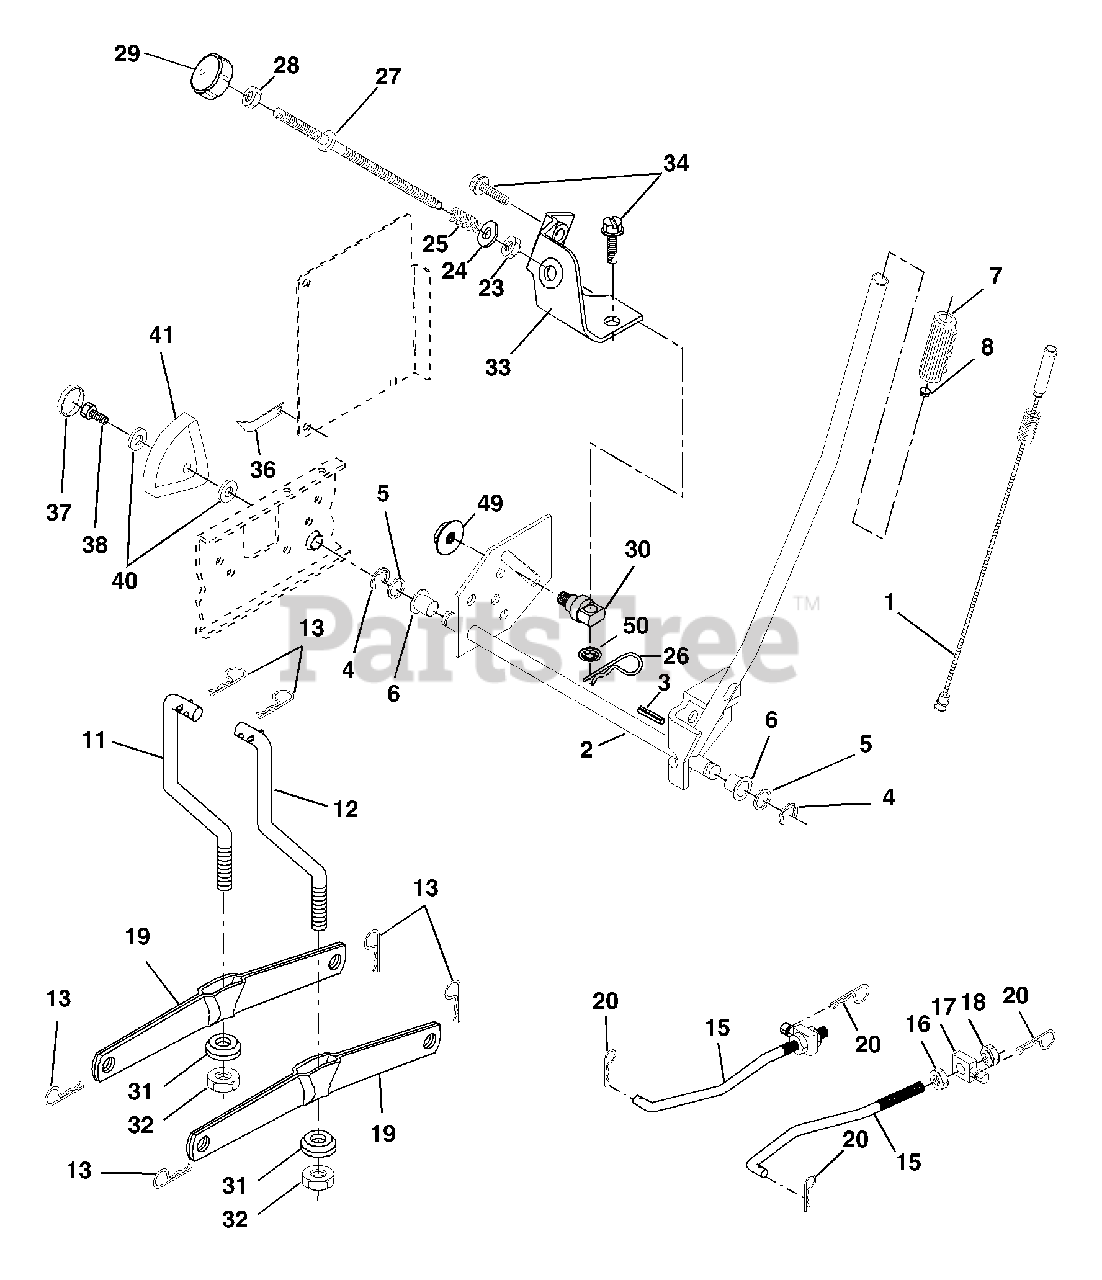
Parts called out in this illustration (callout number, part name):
1	Wire Asm Inner/Sprg W/plunger LT
2	Shaft Asm Lift RH w/Inf
3	Pin Groove 1 500 Zinc
4	E Ring #5133-62
5	Washer 21/32 X 1 X 21 Ga
6	Bearing Nylon Blk 629 Id
7	Grip Handle
8	Button Plunger
11	Link Lift LH Fixed Length
12	Link Lift RH Fixed Length
13	Retainer Spring
15	Link Front
16	Nut Jam Hex 1/2-13 Unc
17	Trunnion Blk Zinc
18	Nut Lock w/Wsh 1/2-13unc
19	Arm Suspension Rear
20	Retainer Spring
23	Nut Special
24	Washer 13/32 X 5/8 X 16 Ga
25	Spring 2-1/8"
26	Retainer Clip
27	Rod Adj Lift Zinc 7.49 Wrk Lg
28	Nut Hex Jam 3/8-16 Unc
29	Knob Inf 3/8-16 Unc Blk W/sym
30	Trunnion Infin Height
31	Bearing Pvt Lift Spherical
32	Nut Crownlock 3/8 - 24
33	Bracket Infinite Height
34	Screw Thdrol 3/8-16 x 1/2
36	Pointer Height Indicator
37	Plug Hole Blk 1.485/1.515 Dia.
38	Screw 5/16-18 x 1
40	Washer 11/32 x 1-1/2 10 Ga.
41	Indicator Height STLT
49	Nut Hex Flange Lock
50	Nut PUsh Phos & Oil
